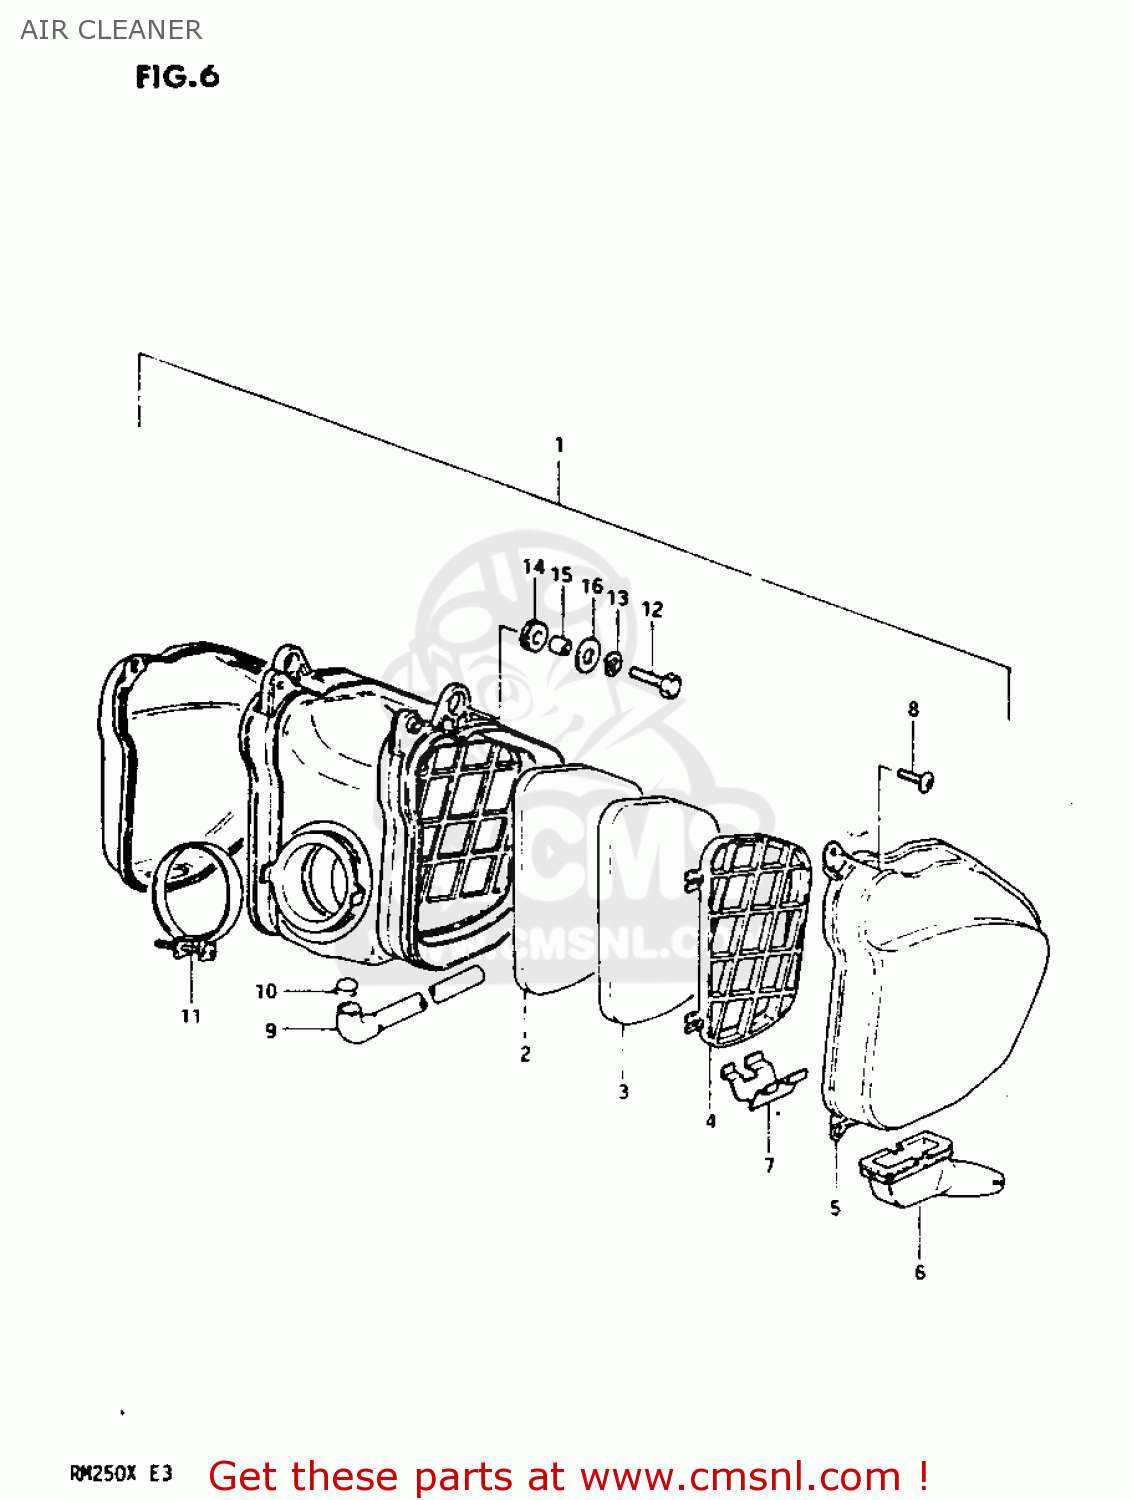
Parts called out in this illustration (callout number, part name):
1	CLEANER ASSEMBLY,AIR
2	FILTER
3	FILTER,2ND
4	HOLDER,AIR CLEANER,LEFT
5	CLEANER ASSEMBLY,AIR
6	DRAIN TUBE
7	DRAIN STOPPER
8	SCREW
9	DRAIN TUBE
10	CLIP
11	CLAMP
12	BOLT
13	WASHER,LOCK
14	CUSHION
15	SPACER (7X9X7)
16	WASHER(6.5X20X1.6)
